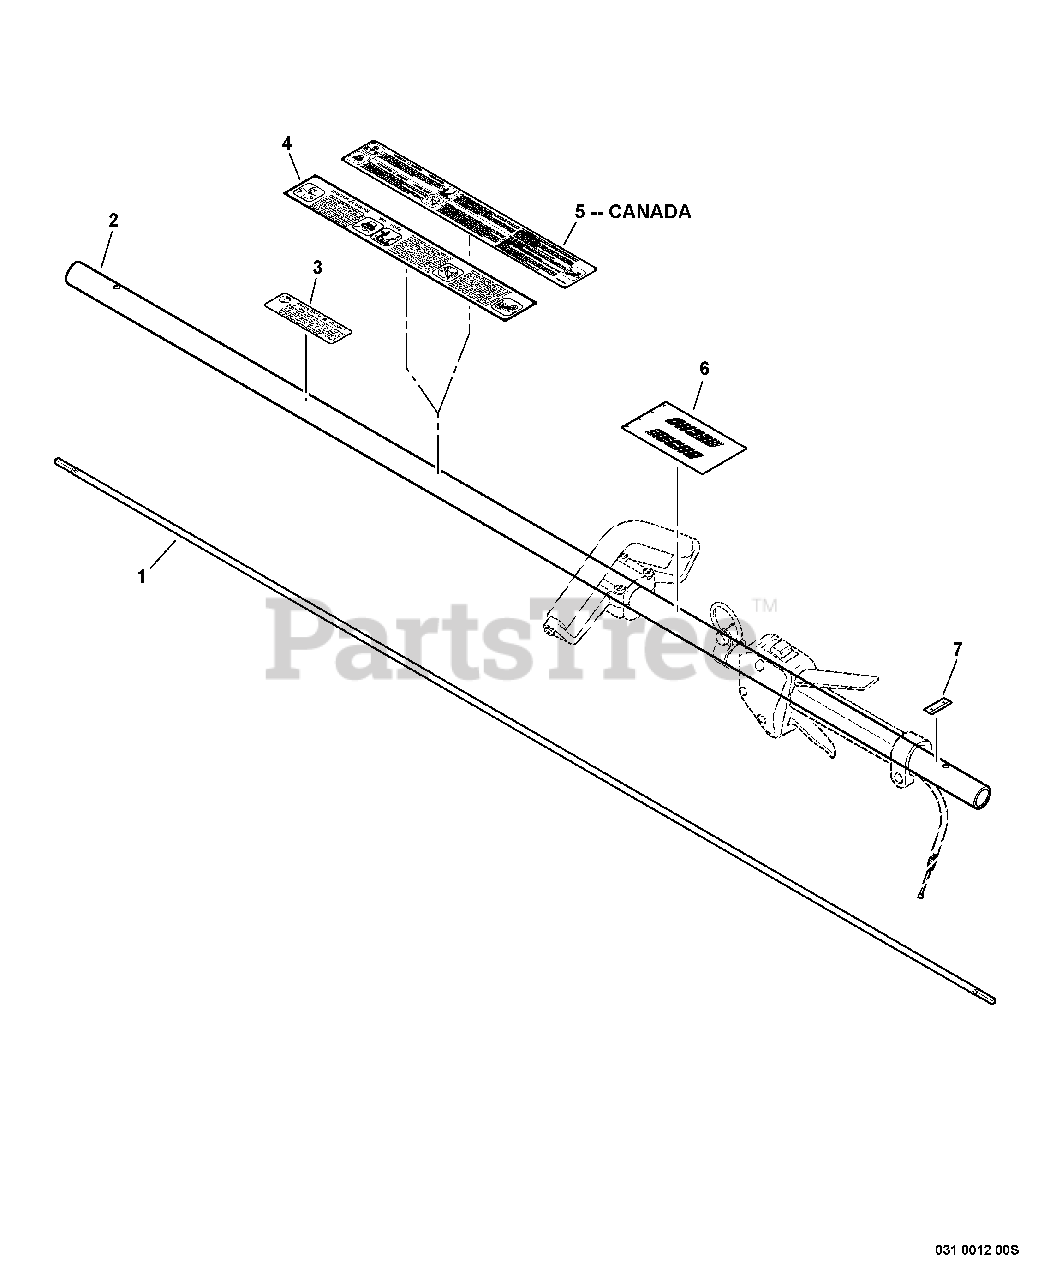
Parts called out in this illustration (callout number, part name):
1	MAINSHAFT
2	PIPE, MAIN
3	LABEL, CAUTION
4	LABEL, CAUTION
5	LABEL, CAUTION
6	LABEL, HANDLE LOCATION
7	LABEL - ALIGNMENT
